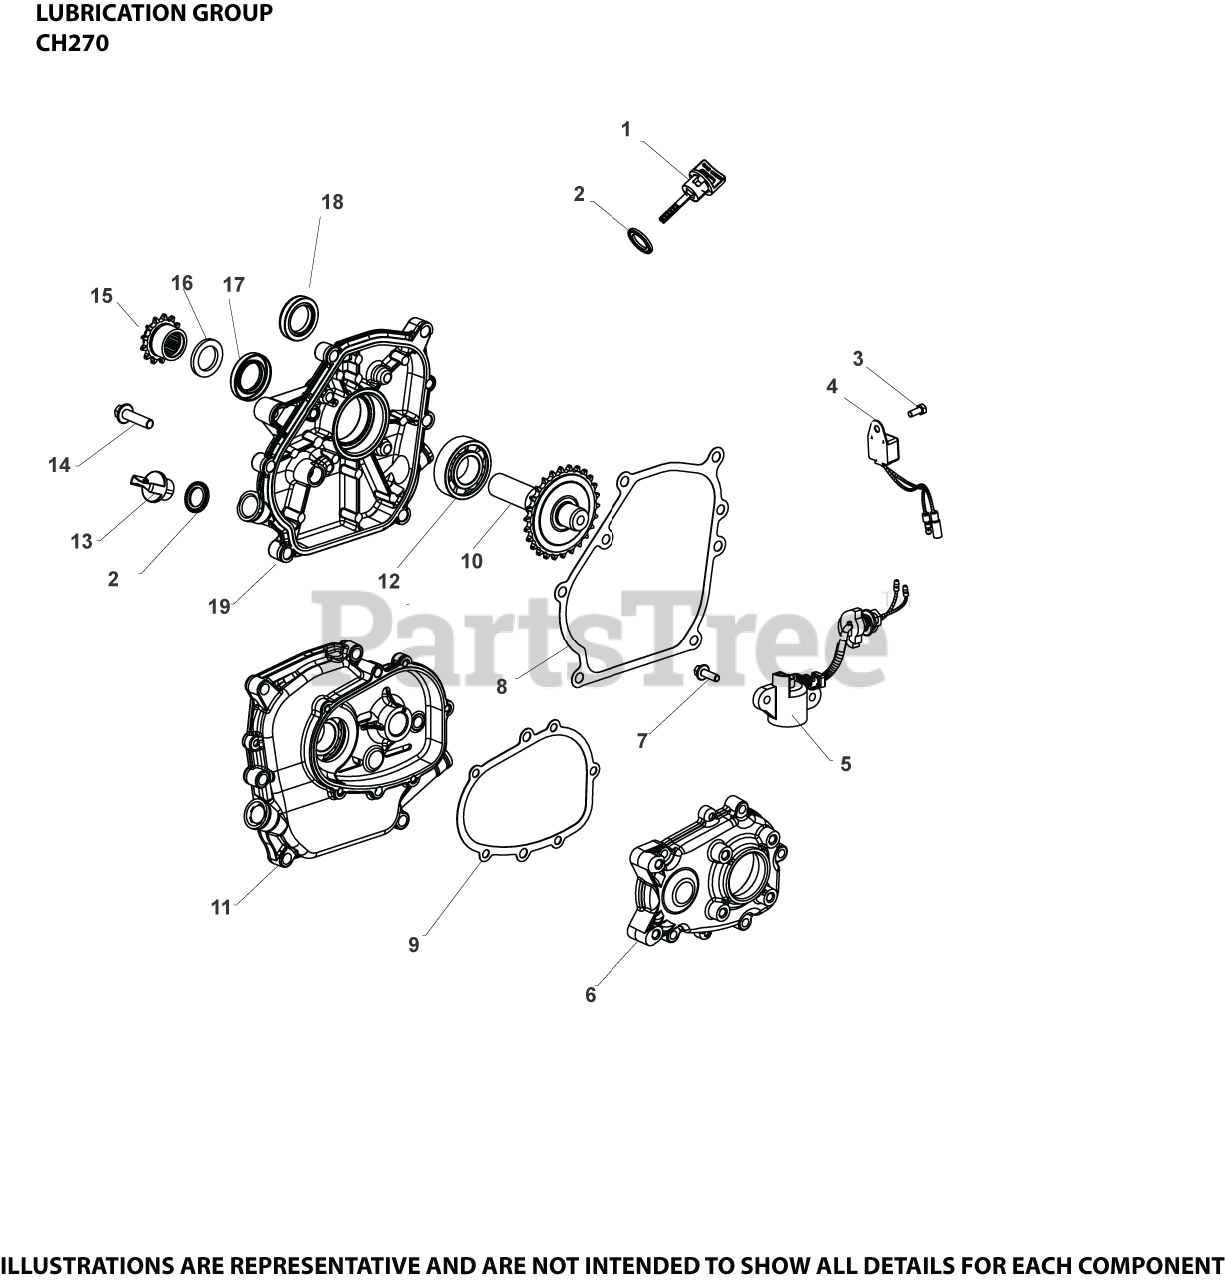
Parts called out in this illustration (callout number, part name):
1	DIPSTICK ASSEMBLY
2	SEAL, OIL
3	SCREW, HEX/PHILLIPS M5
4	CONTROL, OIL ALERT UNIT
5	SWITCH, OIL SENSOR ASSEMBLY
7	SCREW, M6 X18
8	GASKET, CLOSURE PLATE
12	BEARING, BALL
14	SCREW, CLOSURE PLATE
17	SEAL, CLOSURE PLATE
19	KIT, CLOSURE PLATE
